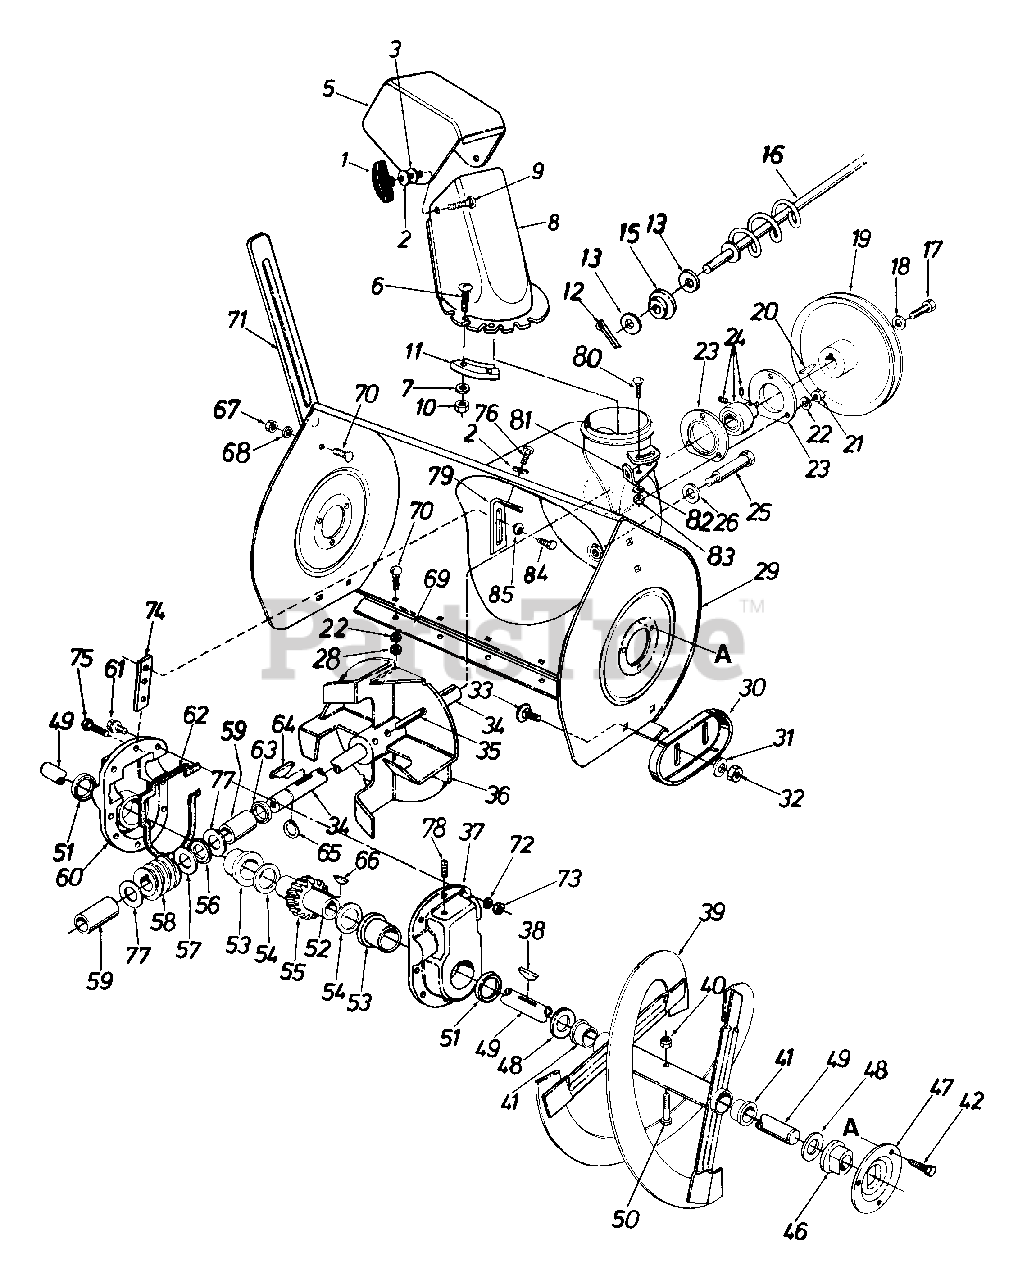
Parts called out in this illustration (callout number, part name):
1	Hand Knob Ass'y.
2	Bell-Wash. .345 I.D. x.88 O.D. x .060
3	Fl. Wash. .312 I.D. x 1.125 O.D. x .125
5	Top Chute
6	Truss Mach. Scr. 1/4-20 x .75"
7	Fl-Wash. 1/4" I.D.
8	Chute
9	Carr. Bolt 5/16-18 x 1.00" Lg.
10	Hex Cent. L-Nut 1/4-20 Thd.
11	Chute Flange Keeper
12	Cotter Pin
13	Fl-Wash. .385" I.D. x.62"
15	Bushing
16	Chute Crank Ass'y.
17	Hex L-Scr. 5/16-18 x .88" Lg.
18	Bell-Wash. .345 I.D. x .88
19	V-Pulley .875 I.D. x 10.12
20	49 Hi-Pro Key 3/16 x 3/4" Dia.
21	Hex Nut 5/16-18 Thd.
22	L-Wash. 5/16" I.D.
23	Bearing Hsg. - Self Aligning Brg.
24	Self Aligning Brg. .875 I.D.
25	Stud 3/8-16 x 2.75" Lg.
26	Bell-Wash. .400 I.D. x .88 O.D. x .060
28	Hex Nut 5/16-18 Thd.
29	Blower Hsg. Ass'y.
30	Slide Shoe
31	Bell-Wash. .400 I.D. x .88 O.D. x .060
32	Hex Jam Nut 3/8-16 Thd.
33	Carr. Bolt 3/8-16 x .62" Lg.
34	Blower Axie
35	Spring Pin Spiral 5/16" Dia. x 1.75" Lg.
38	#91 Woodruff Key 1/4" x 3/4" Dia.
39	Spiral Ass'y.- L.H.
40	Hex Ins. L-Nut 5/16-18 Thd.
41	Plastic Bushing
42	Hex Wash. Hd. Self-Tap Scr. 5/16-24 x .62" Lg.
46	Flange Brg. w/Flats 1.0" I.D.
47	Bearing Hsg. - Spiral Hsg.
48	Fl-Wash. 1.06 I.D. x 1.75" O.D. x .100
49	Spiral Axle
50	Hex Bolt 5/16-18 x 1.75" Lg.
51	Oil Seal 1.50" I.D.
52	Worm Gear Shaft
53	Flange Brg. 1.503 I.D.
54	Fl-Wash. 1.5 I.D. x 2.0 O.D.
55	Double Threaded Worm Gear
56	Thrust Brg. .88 I.D. x 1.44 O.D. x .078
57	Fl-Wash. .88 I.D. x 1.40 O.D.
58	Double Threaded Worm - L.H.
59	Sleeve Brg. .875 I.D.
60	Complete Gear Hsg. Half - R.H.
61	Hex Bolt 5/16-18 x 1.0" Lg.
62	Gasket
63	Oil Seal .875" I.D.
64	#9 Hi-Pro Key 3/16 x 3/4" Dia.
65	Snap Ring -.875" Dia.
66	#91 Woodruff Key 1/4 x 3/4" Dia.
67	Hex Nut 5/16-18 Thd.
68	L-Wash. 5/16" I.D.
70	Carr. Bolt 5/16-18 x .62" Lg.
72	Wave Wash. 5/16" I.D.
73	Hex Ins. L-Nut 5/16-18 Thd.
74	Gear Hsg. Support Plate
75	Hex Bolt 5/16-18 x 1.25"
76	Hex Wash. Hd. Self-Tap Scr. 5/16-18 x .75" Lg.
77	Fl-Wash. .88 I.D. x 1.40 O.D.
78	Filler Plug
80	Carr. Bolt 5/16-18 x .75" Lg.
82	Bell-Wash. .345 I.D. x.88"
83	Hex Nut 5/16-18 Thd.
84	Hex Bolt 1/4-28 x .75" Lg.
85	Bell-Wash. .28" I.D. x .75" O.D.
